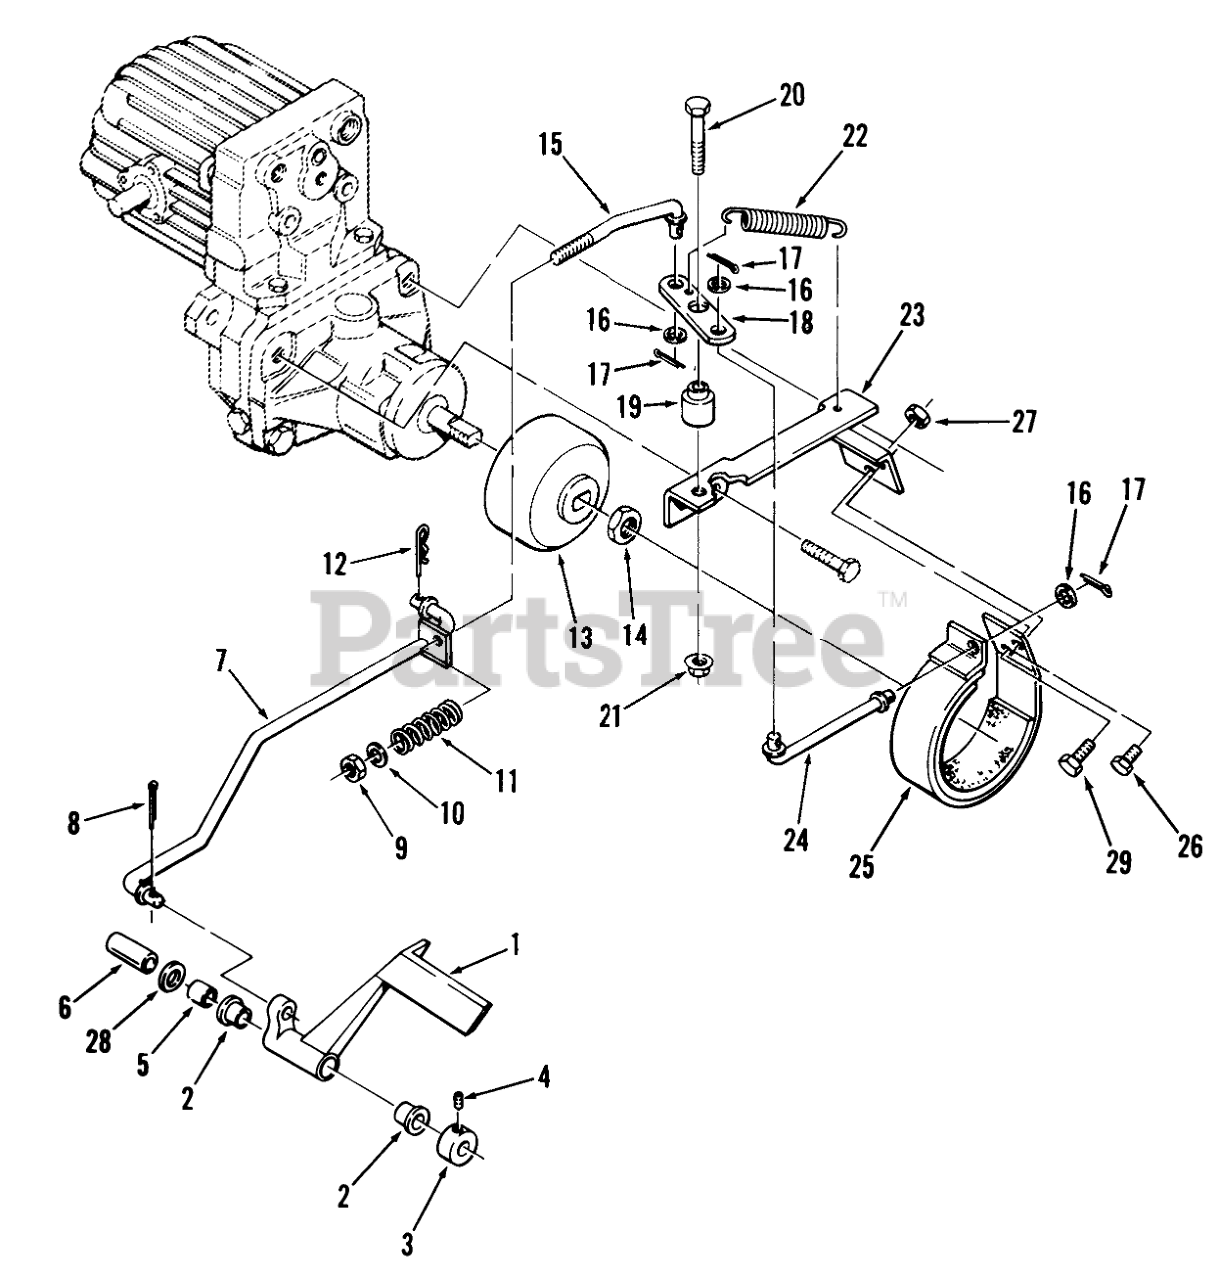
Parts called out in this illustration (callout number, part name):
1	PEDAL R
2	BUSHING
3	Collar
4	SCREW-SET
5	Spacer
6	SPACER
7	Brake Rod-Front
7	BRAKE ROD ASSY R
9	Nut
10	Washer
11	SPRING
13	ASSY-BRAKE DRUM
14	E.S. Nut 9/16-18 Thin
16	Washer
17	Pop Rivet
18	Lever
19	SPACER
20	BOLT
21	Nut
22	CLUTCH SPRING
23	Brake Bracket
25	BRAKE BAND ASM
26	H H C S
27	Nut
28	Washer
29	Bolt
